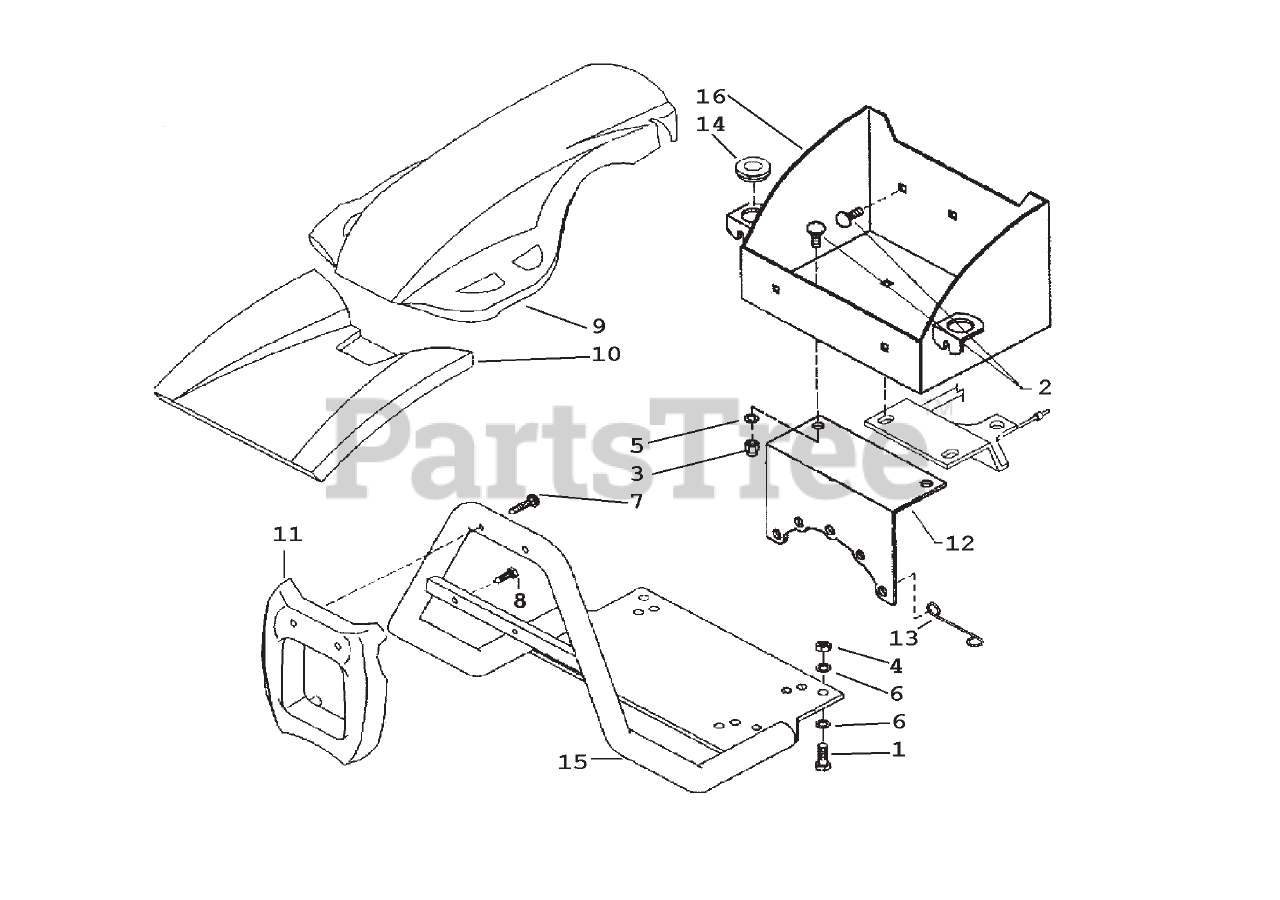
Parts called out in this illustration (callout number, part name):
1	CAPSCREW, M8X40 UNI 57398G
2	BOLT, M6 X 16
3	NUT, LOCK M6
4	NUT, LOCK M8
5	WASHER, FLAT, M6 4X12
6	WASHER, FLAT, M8 4X17
7	SCREW, SELF TAPPING, M6.3X38
8	SCREW, SELF TAPPING, M6.3X19
9	COVER, HANDLEBAR
10	GUARD, LOWER
11	FRONT BUMPER GUARD
12	BATTERY/TOOL BOX SUPPORT
13	SUPPORT, GAS CABLE SHEATH
15A	BUMPER
15B	BUMPER
16A	SUPPORT, LOWER GUARD
16B	BATTERY BOX, ELECTRIC START
